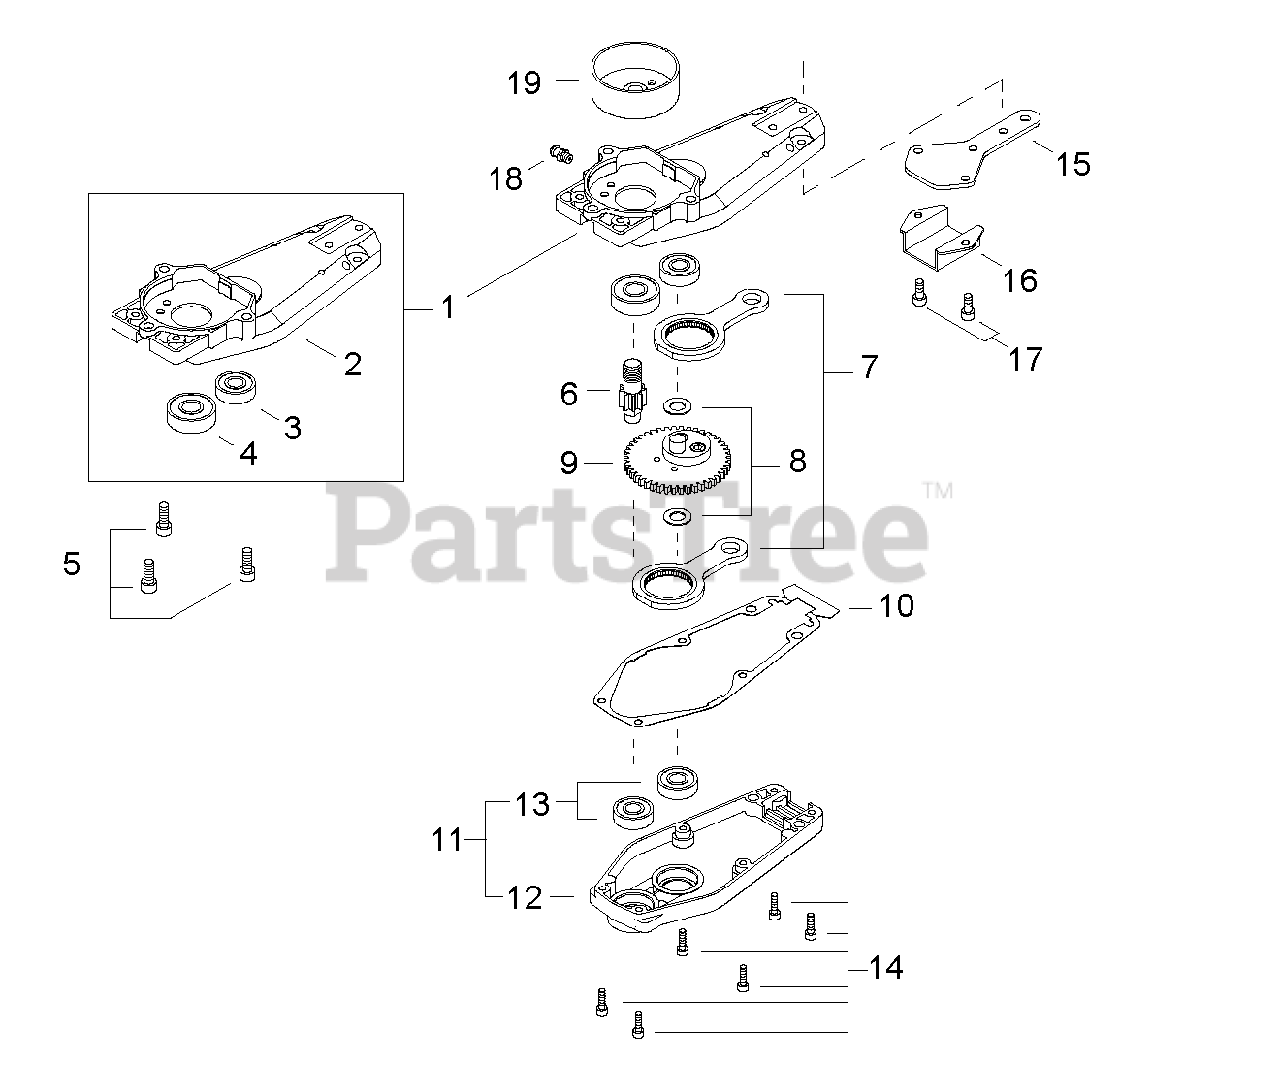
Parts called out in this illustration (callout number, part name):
1	GEAR CASE HOUSING ASSY
2	HOUSING, GEAR CASE
3	BEARING, BALL 6000ZZ
4	BEARING, BALL 6201
5	BOLT 6×16
6	SHAFT, PINION
8	WASHER 10
9	CAM GEAR ASSY
10	GASKET, GEAR CASE
11	COVER ASSY, GEAR CASE
12	COVER, GEAR CASE
13	BEARING, BALL 6000ZZ
14	BOLT 4×14
15	PLATE, EYE
16	GUIDE, BLADE
17	BOLT 5×12
18	FITTING, GREASE
19	DRUM, CLUTCH
